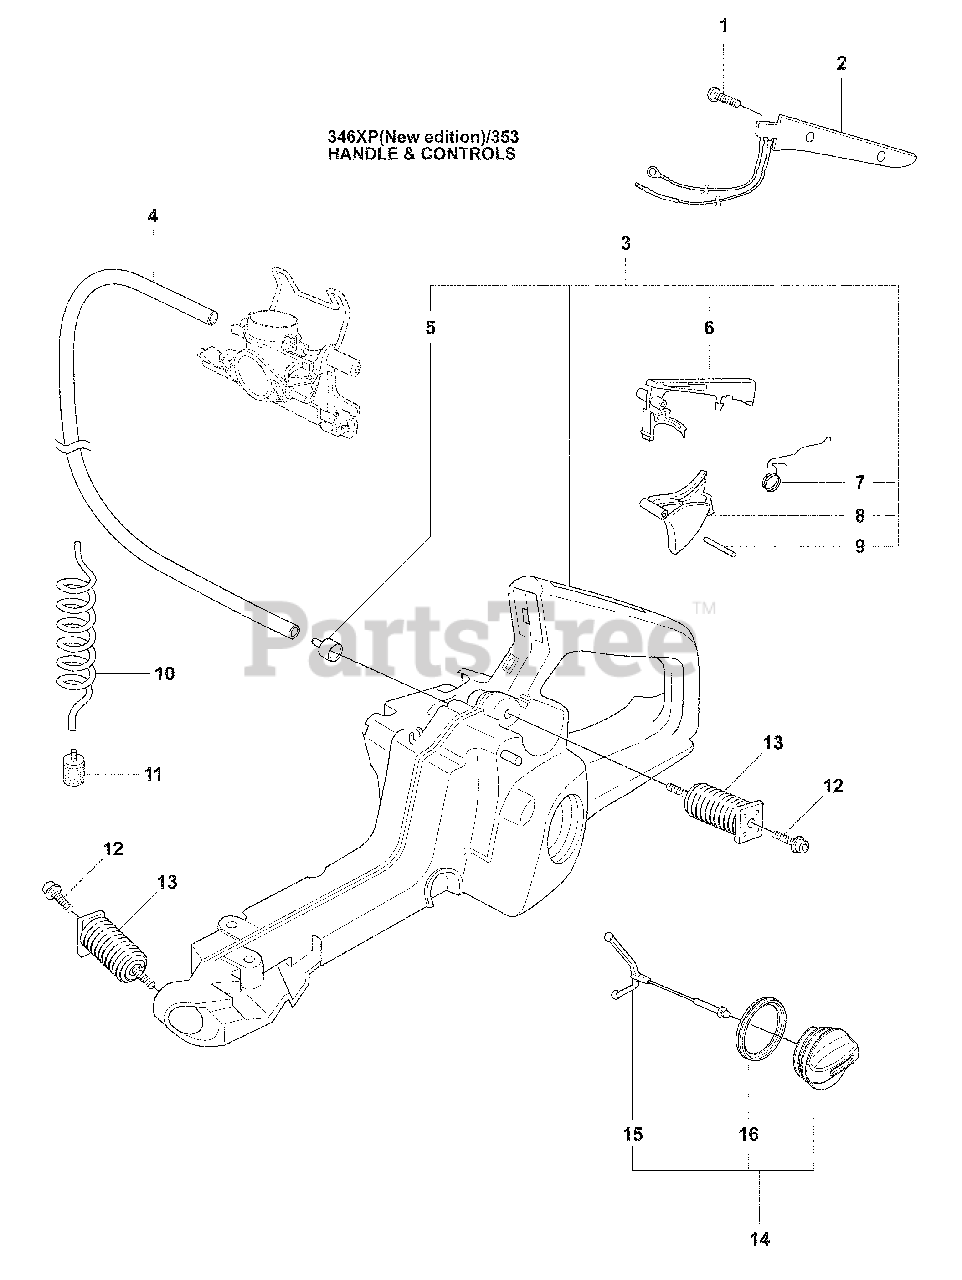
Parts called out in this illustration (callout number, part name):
4	Fuel Hose, Straight 120
5	Tank Vent Assembly
6	Throttle Lock
10	Fuel Hose, Spiral 300
11	Fuel Filter Kit
12	Screw, 3 X 25 IHSCFT
13	Vibration Absorber
14	Std
14	E-tech
16	Sealing Gasket
